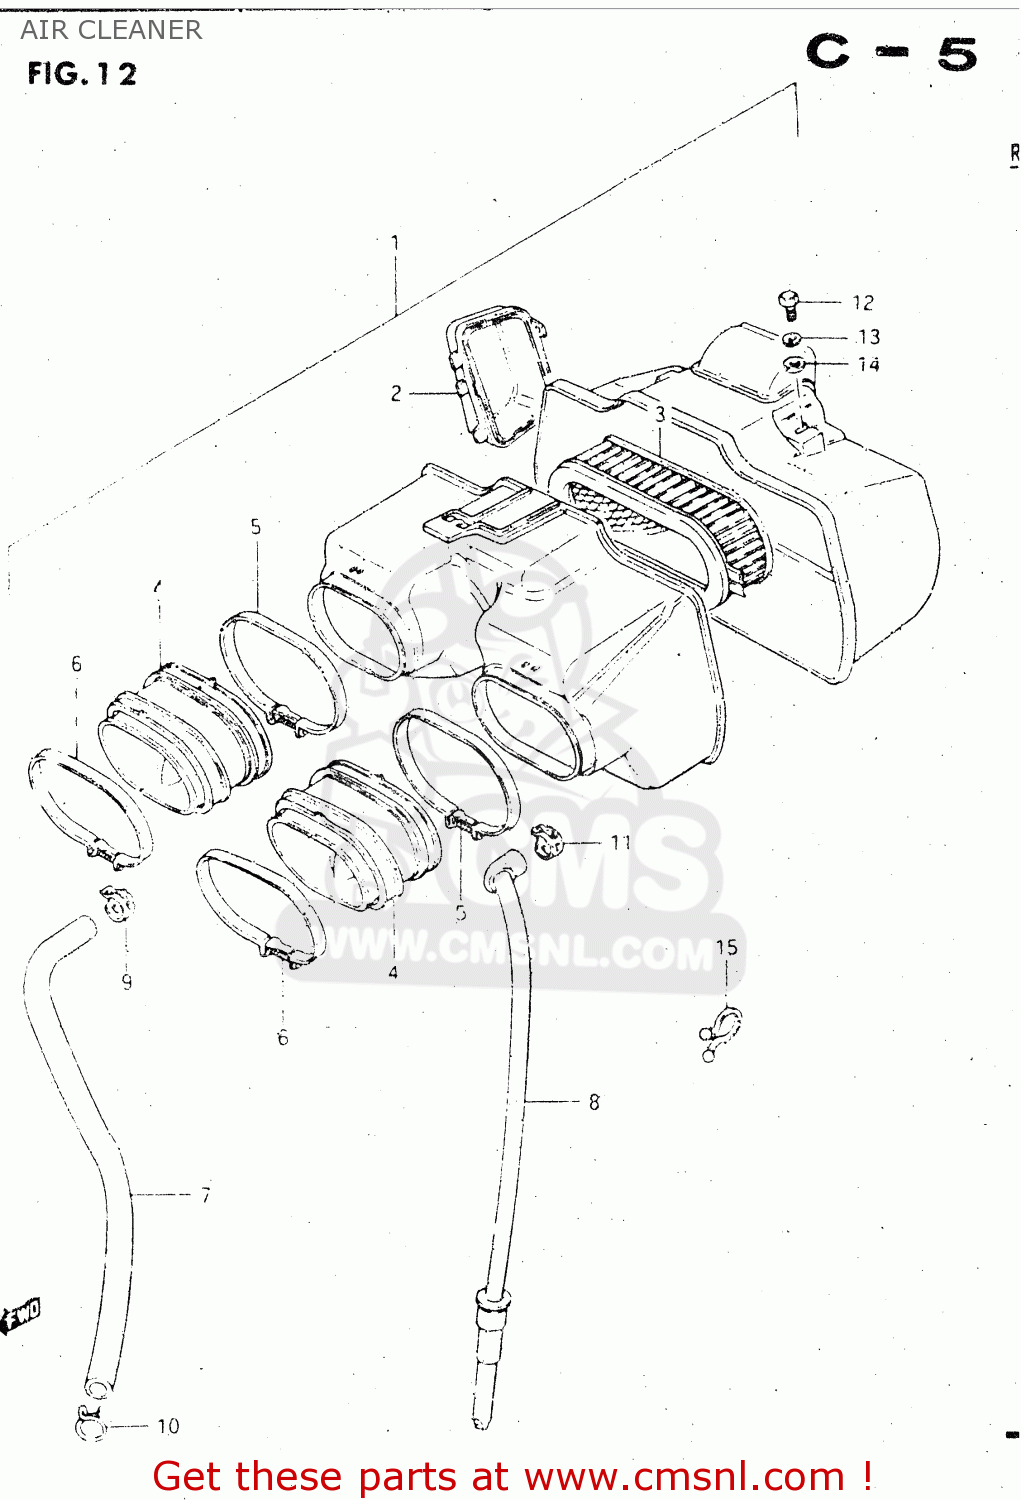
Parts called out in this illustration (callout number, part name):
1	CLEANER ASSEMBLY,AIR
2	CAP,AIR CLEANER
3	FILTER,AIR CLEANER
4	TUBE,AIR CLEANER OUTLET
5	CLAMP,AIR CLEANER
6	CLAMP,CARBURETOR SIDE
7	TUBE,BREATHER
8	DRAIN TUBE
9	CLIP
10	CLIP,BREATHER TUBE
11	CLIP
12	BOLT, UPPER
13	LOCK WASHER
14	WASHER
15	CLIP(ID:16)
